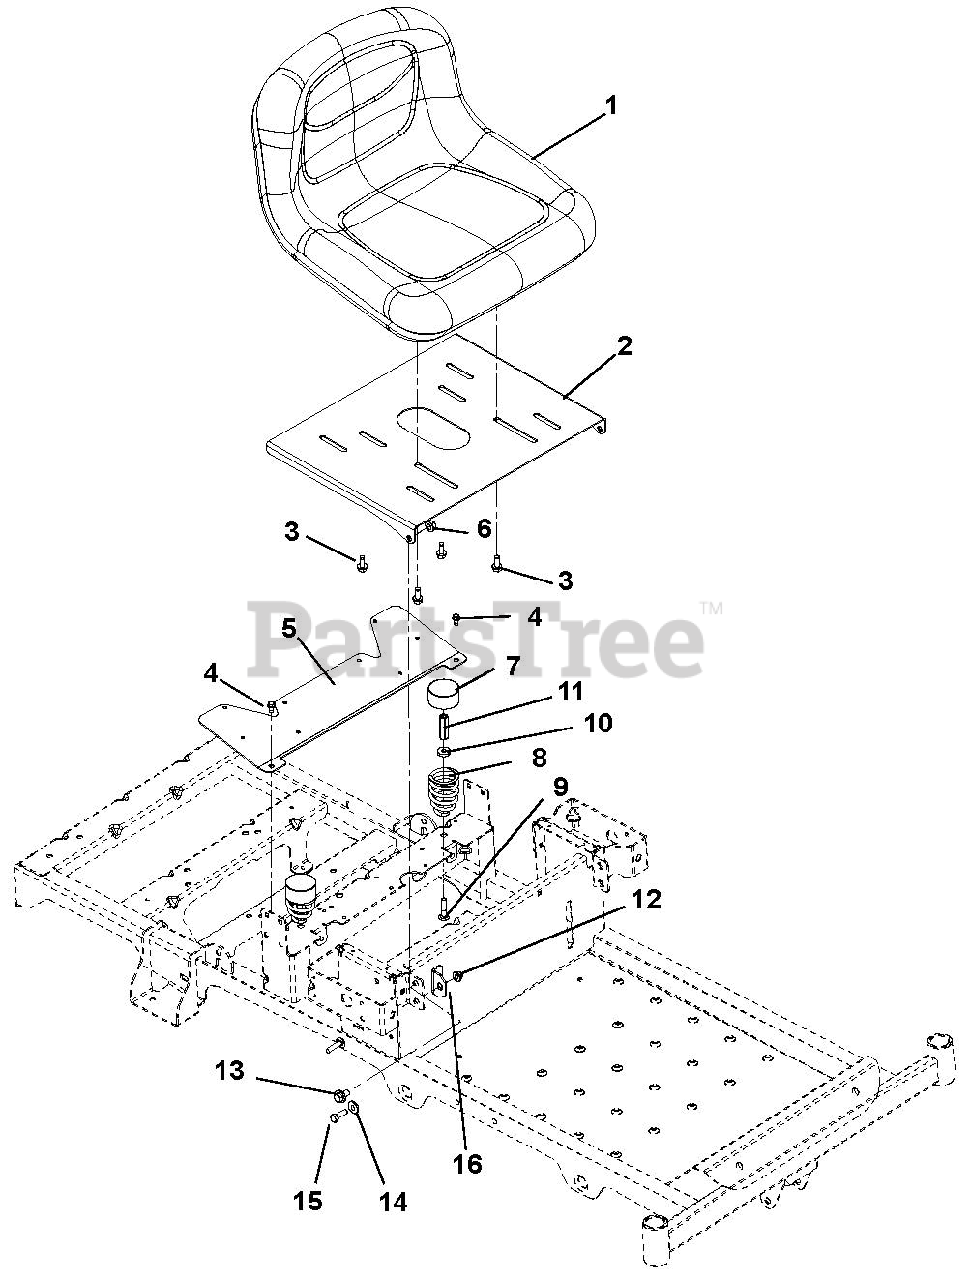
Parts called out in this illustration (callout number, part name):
1	SEAT-13" GREY
2	PLATE, SEAT
3	5/16-18X3/4 HX/W/HD WHIZ
4	@SCR-TAP .25-20X.50 HWH TR YWZ
5	GUARD, FAN
6	@NUT-LK-TOP-FLG .38-16 YWZC
7	HUB CAP
8	SPRING, SEAT
9	@BLT-RDHDSQNK .31-18X1.50 G5YZ
10	WSHR-FL-STL .328X.87X.179 YWZC
11	NUT, COUPLING 5/16-18 X 1 3/4
12	@NUT-LK-NYL-FLG .31-18 YWZC
13	BOLT-SHLDR .375-16X.150
14	BSHG, FLG .325X.499X.26X.88
15	@BLT-HEX .31-18X1.00 GR5 YWZC
16	BRKT, SEAT STOP
